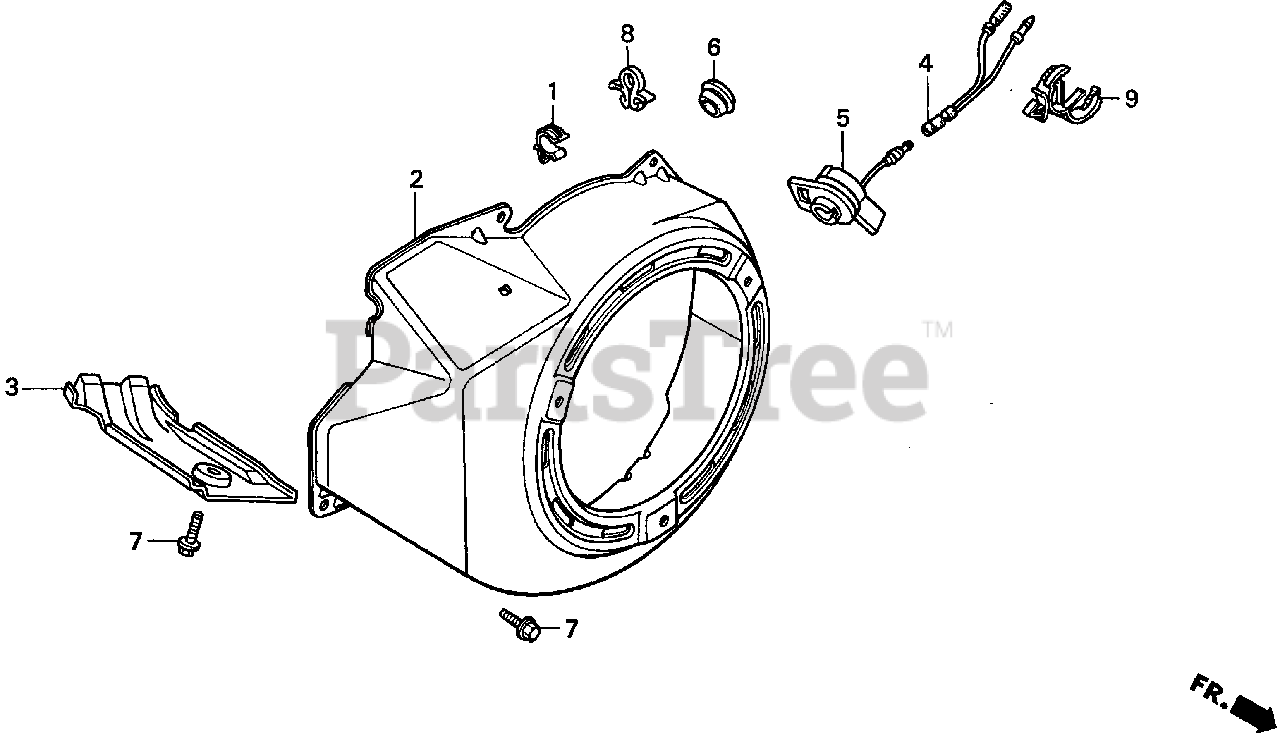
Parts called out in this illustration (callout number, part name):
1	CLIP, TUBE
2	COVER, FAN *R8* (BRIGHT RED)
3	SHROUD
4	SUB-HARNESS
5	SWITCH ASSY., ENGINE STOP
7	BOLT, FLANGE (6X12) (CT200)
9	CLIP, WIRE HARNESS
